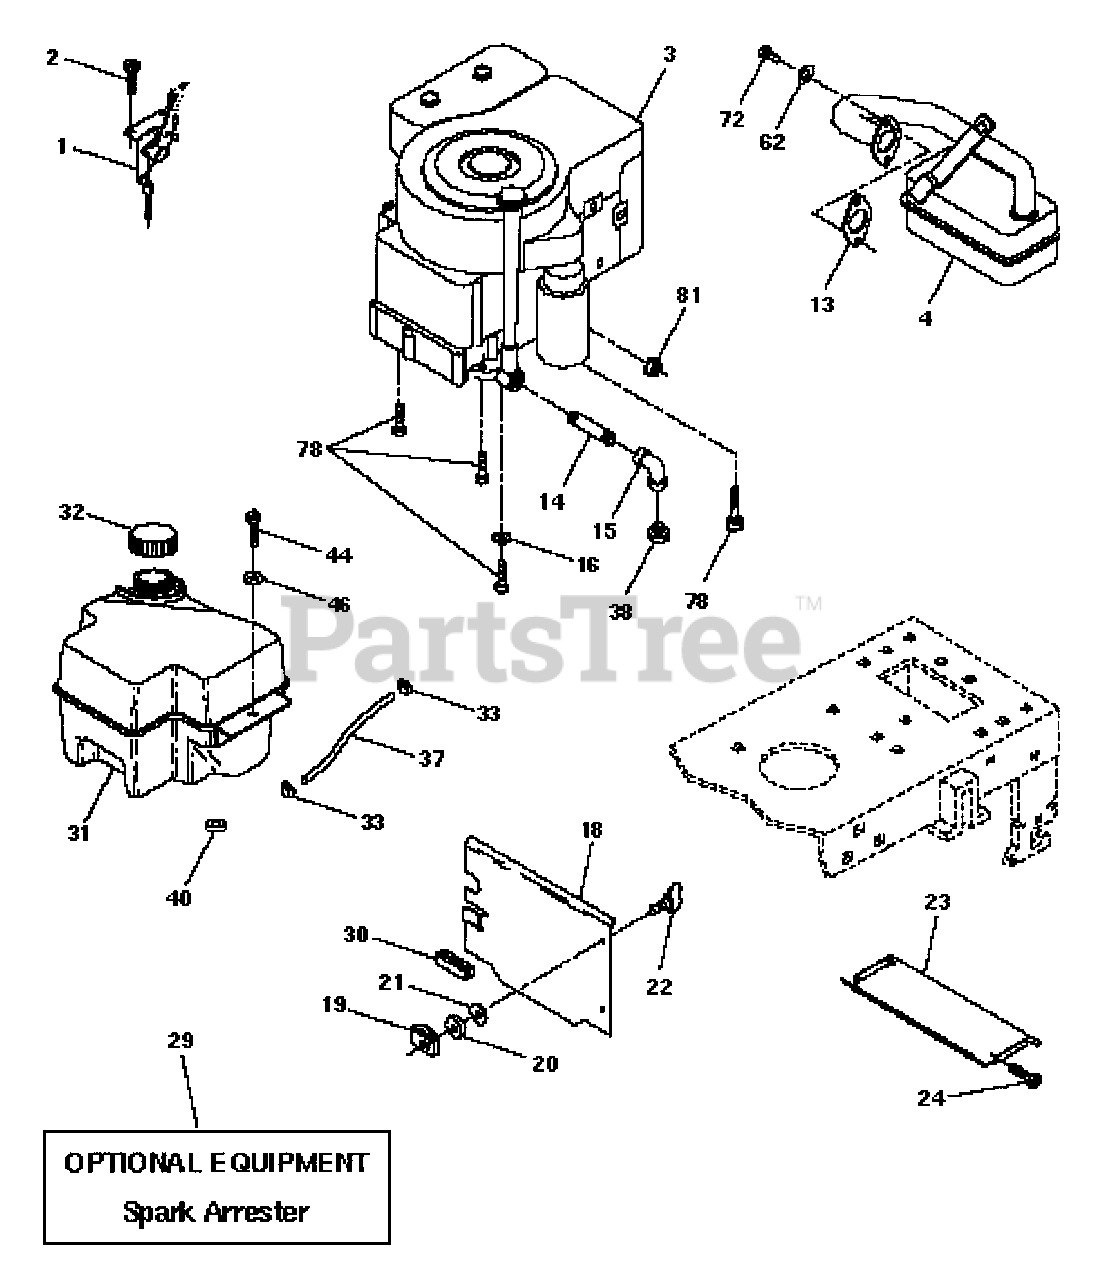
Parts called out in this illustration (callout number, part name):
1	Control Th/ch 23 5 LH Flag
2	Screw Hex Thd Cut 1/4-20x5/8 T
4	Muffler LT B&S 12/12.5/13HP
13	Gasket Eng 1 313 Id Tin Plated
14	Nipple Pipe 3/8 Npt X 3"
15	Elbow Std 90 Degree 3/8-18 Npt
16	Washer Lock Ext Tooth 3/8
18	Shield Heat Lt
19	Receptacle 1/4 turn
20	Retainer 1/4 turn
21	Washer 9/32 x 5/8 x 16 Ga.
22	Stud 1/4 turn
23	Shield Heat Browning LT/YT
24	Screw Tap Hex #10-24unc X 1/2
29	Kit Spark Arrestor (Flat Scrn)
30	Pinch Weld Hood Black
31	Tank Fuel Front 2 00
32	Cap Asm Fuel W/sym Vented
33	Clamp Hose Black
37	Line Fuel 20"
38	Plug Oil Drain
40	Bushing Snap Nyl Blk Fuel Line
44	Screw Hexwsh Thdrol 1/4-20x3/4
46	Washer 9/32 X 7/8 X 16 Ga
62	Washer Lock Hvy Hlcl Spr 5/16
72	Screw Hexhd Cap 5/16-18x 3/4
78	Screw Thdrol 3/8-16x1-1/4 TYTT
81	Nut Keps Hex 1/4-20 Unc
